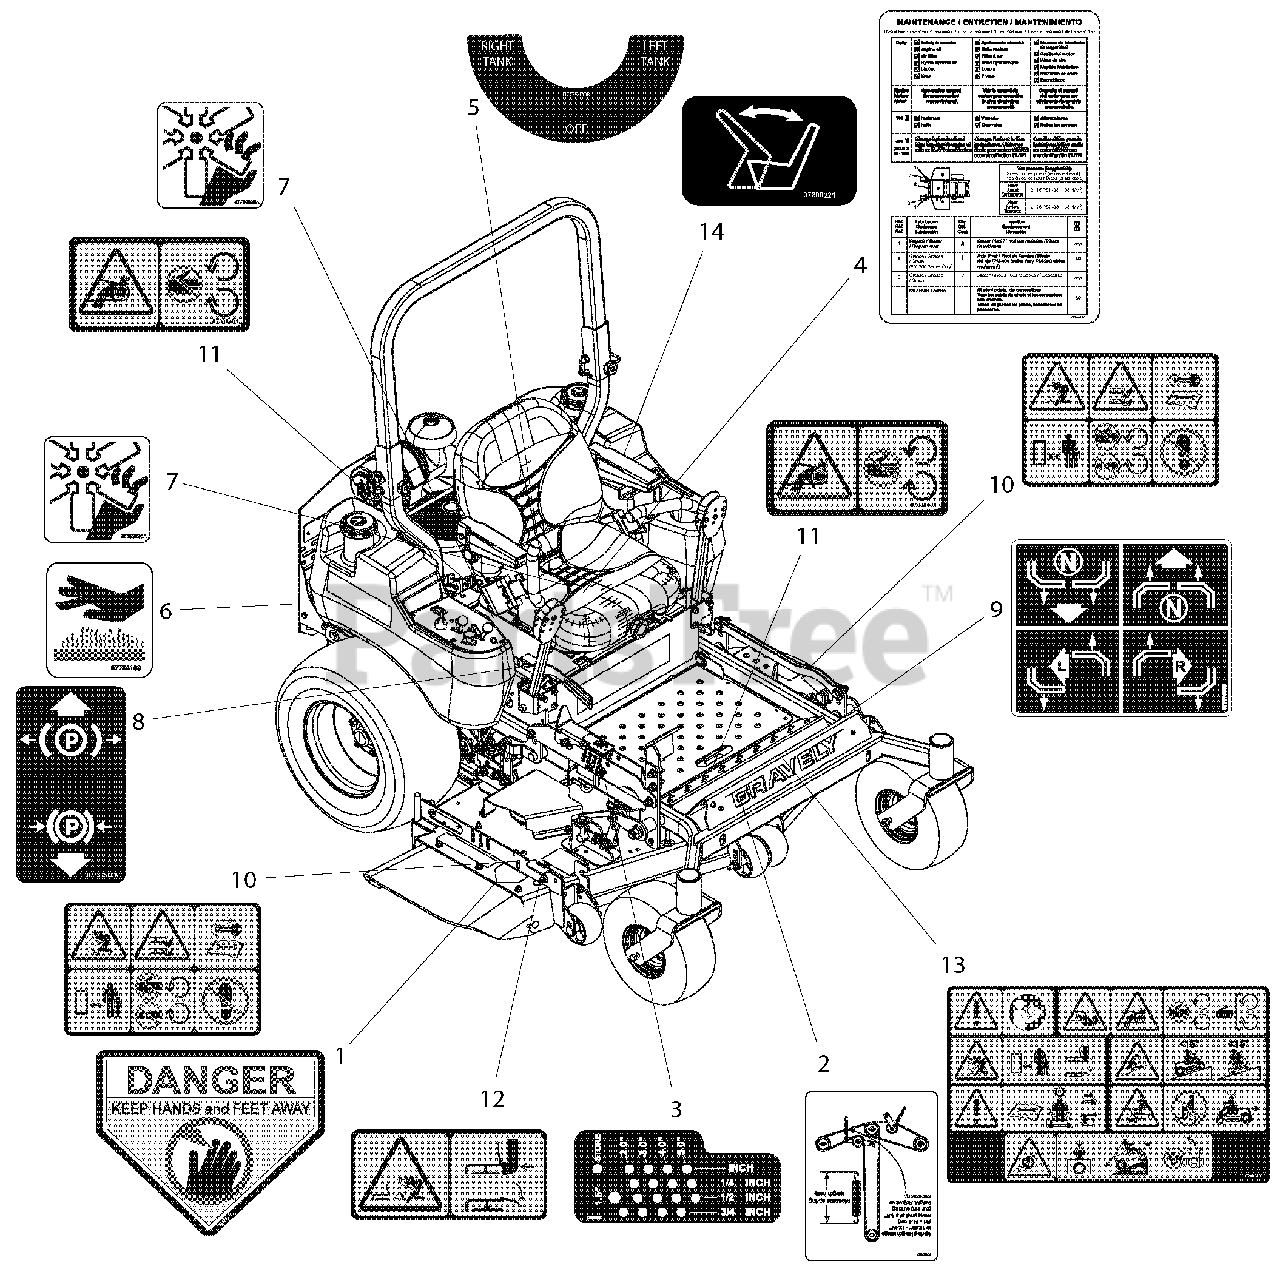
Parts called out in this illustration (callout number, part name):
1	DECAL, DANGER
2	DECAL, BELT ROUTING
3	DECAL, HEIGHT OF CUT
4	DECAL, MAINTENANCE
5	DECAL, FUEL CONTROL VALVE
6	DECAL HOT SURFACE
7	DECAL, DANGER - FAN
8	DECAL, PARKING BRAKE LEVER
9	DECAL, INSTRUCTIONAL - STEERING
10	DECAL, SAFETY - MOWER DECK
11	DECAL, SAFETY - GUARDING
12	DECAL, SAFETY - DECK GUARDING
13	DECAL, MAIN SAFETY, COMMERCIAL
14	DECAL, SEAT RELEASE
